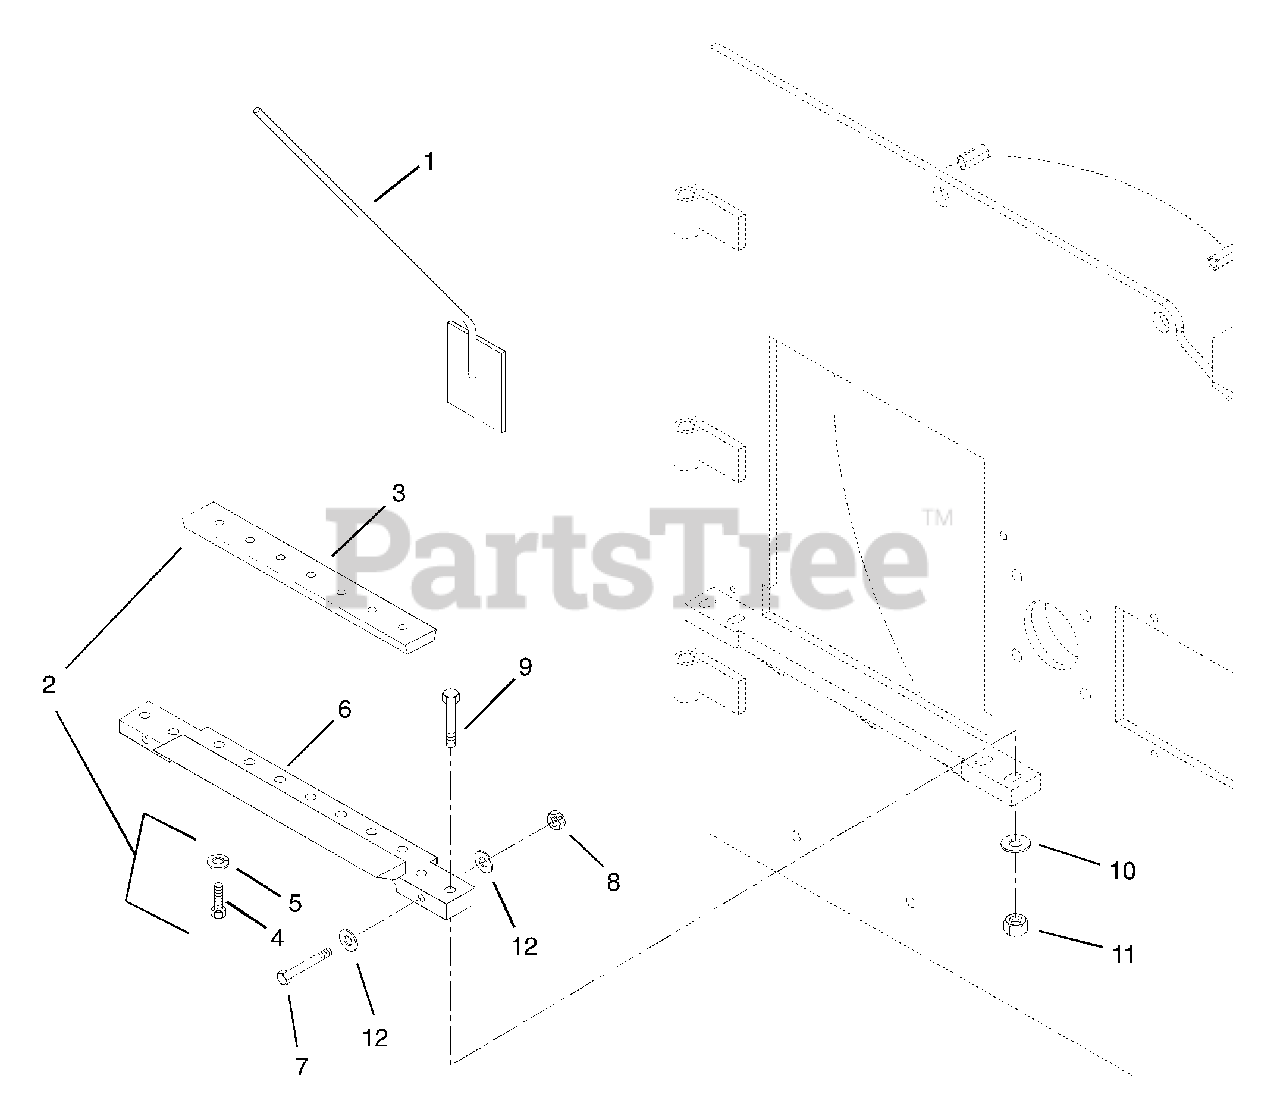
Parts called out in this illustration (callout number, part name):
1	Knife Gauge
2	Bed Knife Kit
4	Bolt-Hex .50-13 x 1.25 Grade 8
5	Washer-Lock .50 x .125
6	Adjustment Bar
7	Bolt-Hex .38-16 x 2.75 Grade 5
8	Nut-Locking-Center .38-16
9	Bolt-Hex .50-13 x 2.75 Grade 8
10	Washer-Flat-Steel .563 x 1.38 x .109
11	Nut-Locking .50-13
12	Washer-Flat-Steel .406 x .812 x .065
